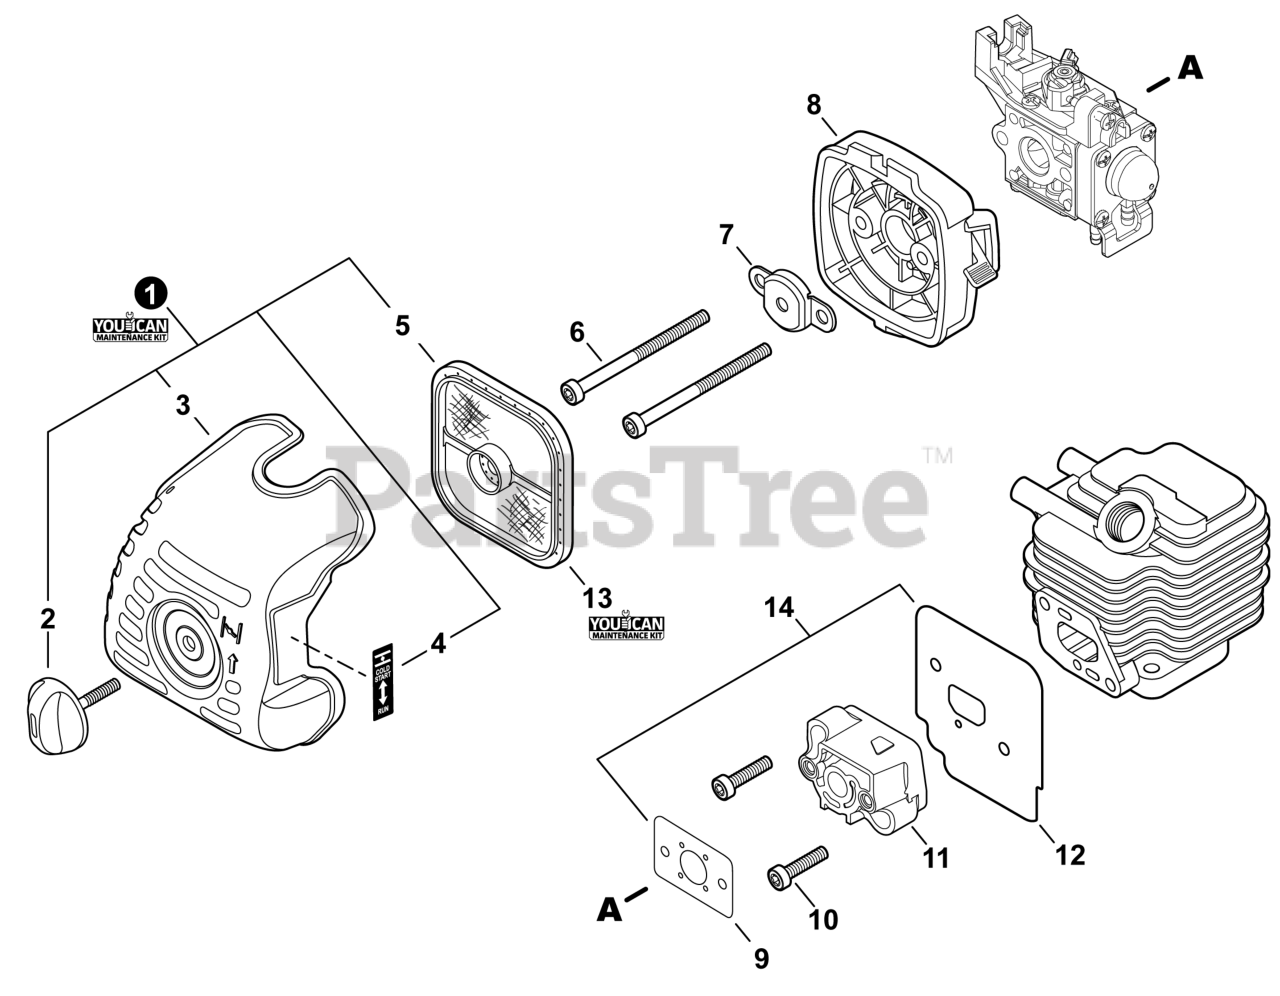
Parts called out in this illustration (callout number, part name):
1	FILTER KIT, AIR - YOUCANT
2	THUMBSCREW
3	COVER, AIR FILTER
4	LABEL - CHOKE
5	FILTER, AIR - DOUBLE LAYER
6	BOLT, TORX 5x55
7	PLATE, PREVENT
8	CASE ASSY, AIR FILTER
9	GASKET, INTAKE
10	BOLT, TORX 5x20
11	INSULATOR, INTAKE
12	HEAT SHIELD, INTAKE
13	TUNE-UP KIT - YOUCANT
14	GASKET KIT: ENGINE, INTAKE, EXHAUST
